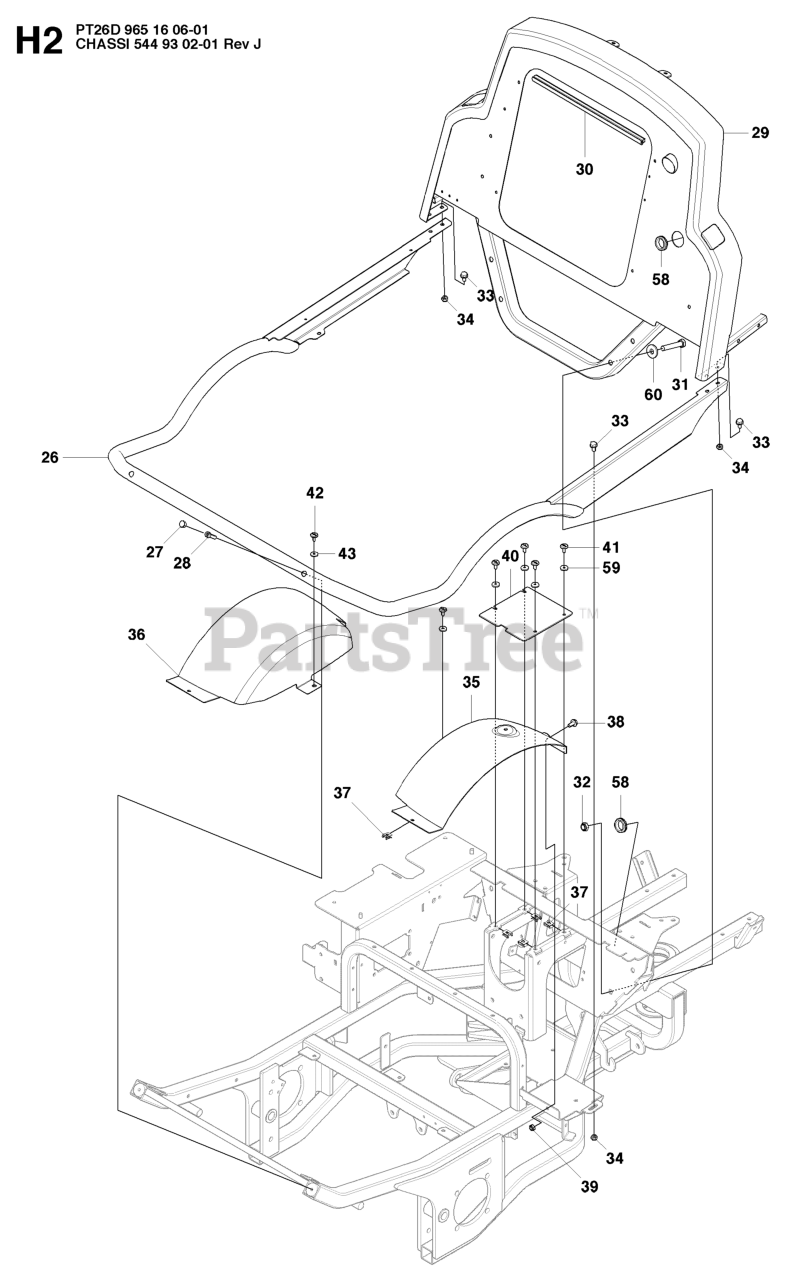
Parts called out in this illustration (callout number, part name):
34	LOCKNUT M8
35	FENDER LEFT
36	FENDER RIGHT
39	LOCKNUT M8
